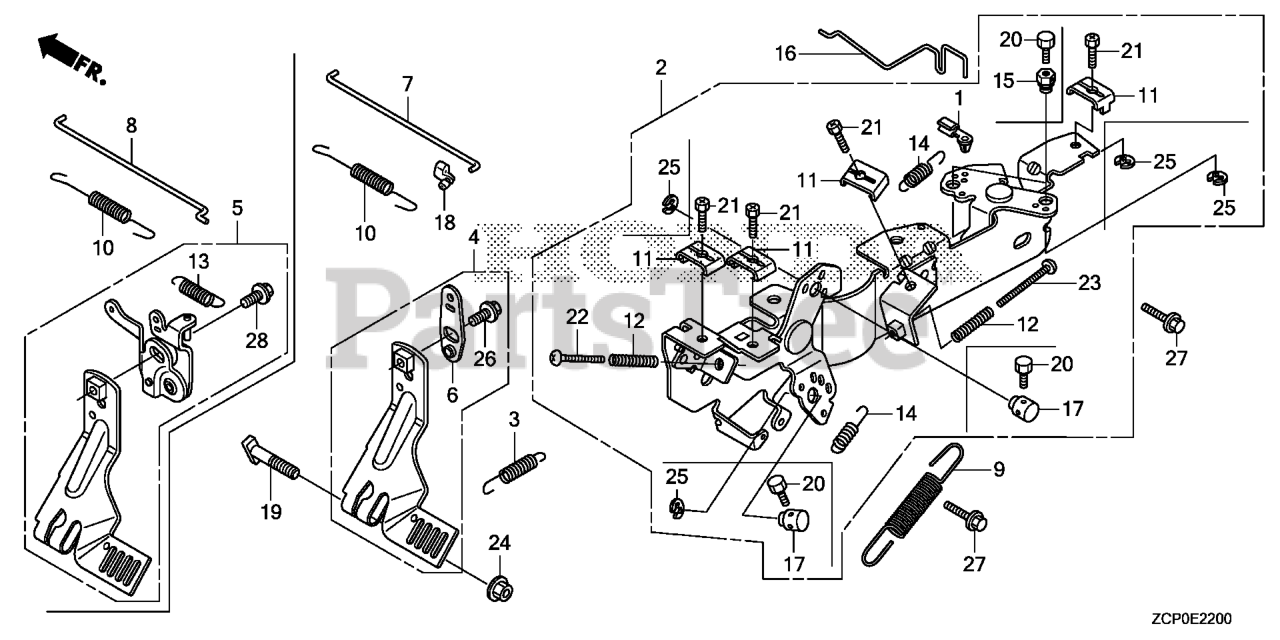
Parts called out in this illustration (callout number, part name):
1	JOINT, ROD
2	CONTROL ASSY.
3	SPRING, STARTER
4	ARM, GOVERNOR
6	ARM, SUB
7	ROD, GOVERNOR
9	SPRING, GOVERNOR
10	SPRING, THROTTLE RETURN
11	HOLDER, CABLE
12	SPRING, CONTROL ADJUSTING Use from Engine SN 2327377.
14	SPRING, CABLE RETURN
16	ROD, CHOKE CONTROL
17	HOLDER, CABLE
18	BUSH, LINKAGE
19	BOLT, GOVERNOR ARM
20	BOLT, RECESSED (4X6)
21	BOLT, RECESSED (5X16)
22	SCREW, PAN (5X30)
23	SCREW, PAN (5X45)
24	NUT, FLANGE (6MM)
25	E-RING (5MM)
26	BOLT, FLANGE (6X10)
27	BOLT, FLANGE (6X14)
